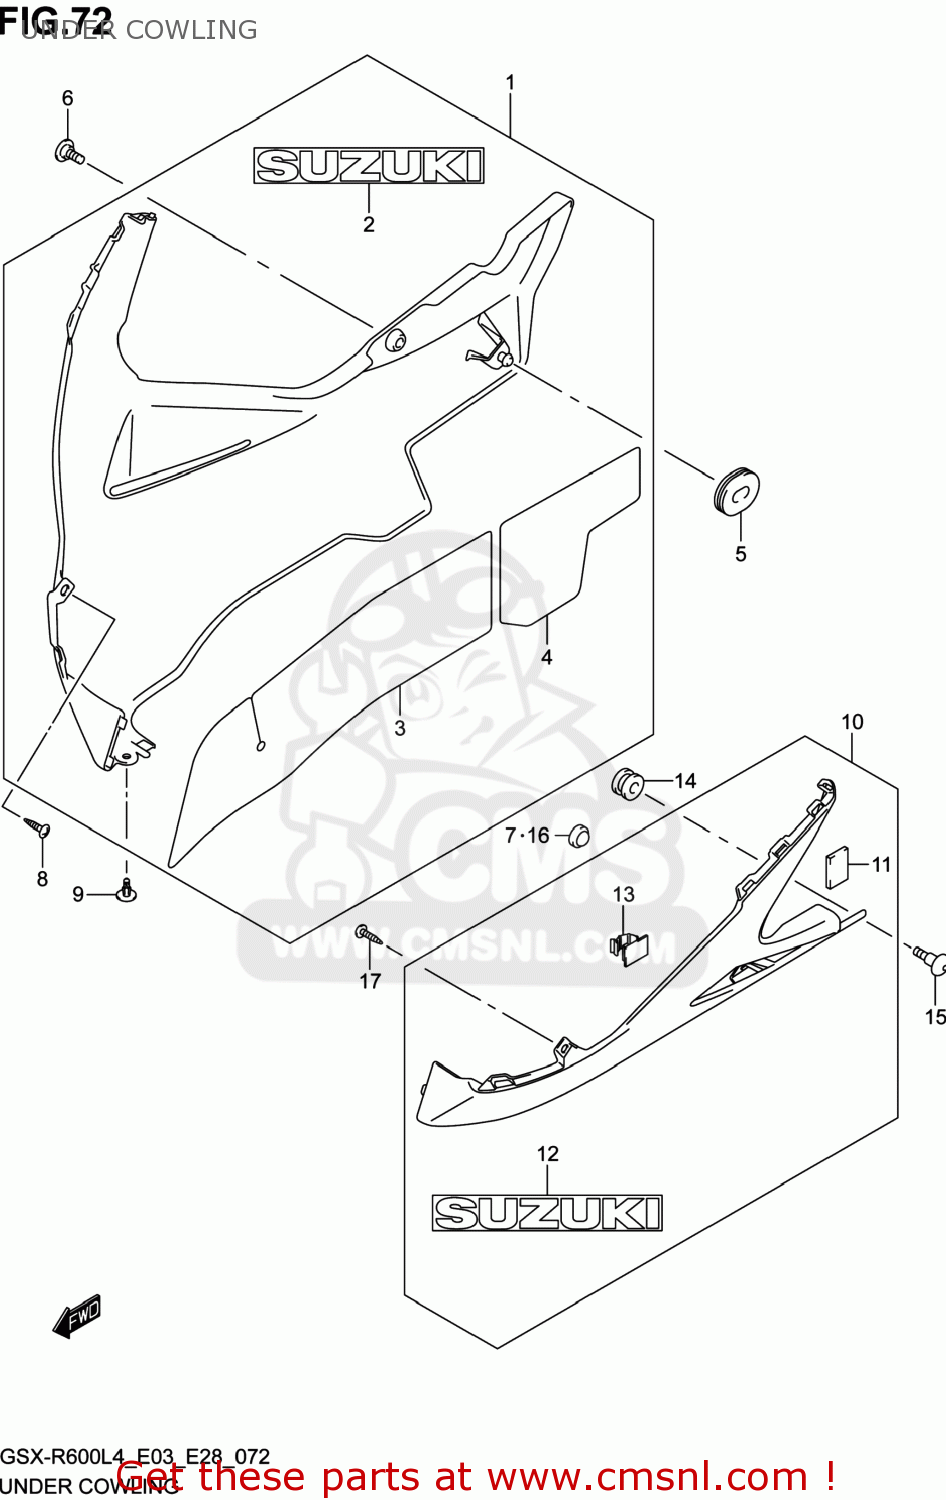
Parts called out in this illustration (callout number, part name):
1	COWLING,UNDER,R(WHITE)
2	EMBLEM,SUZUKI
3	SHIELD,UNDER COWL HEAT,R
4	SHIELD,UNDER COWL HEAT,R
5	CUSHION,UNDER COWLING,R
6	SCREW,UNDER COWL,R
7	CUSHION
8	SCREW
9	CLIP
10	COWLING,UNDER,L(WHITE)
11	CUSHION,BRACKET NO.1
12	EMBLEM,SUZUKI
13	CLAMP
14	CUSHION
15	BOLT(6X20)
16	CUSHION
17	SCREW
